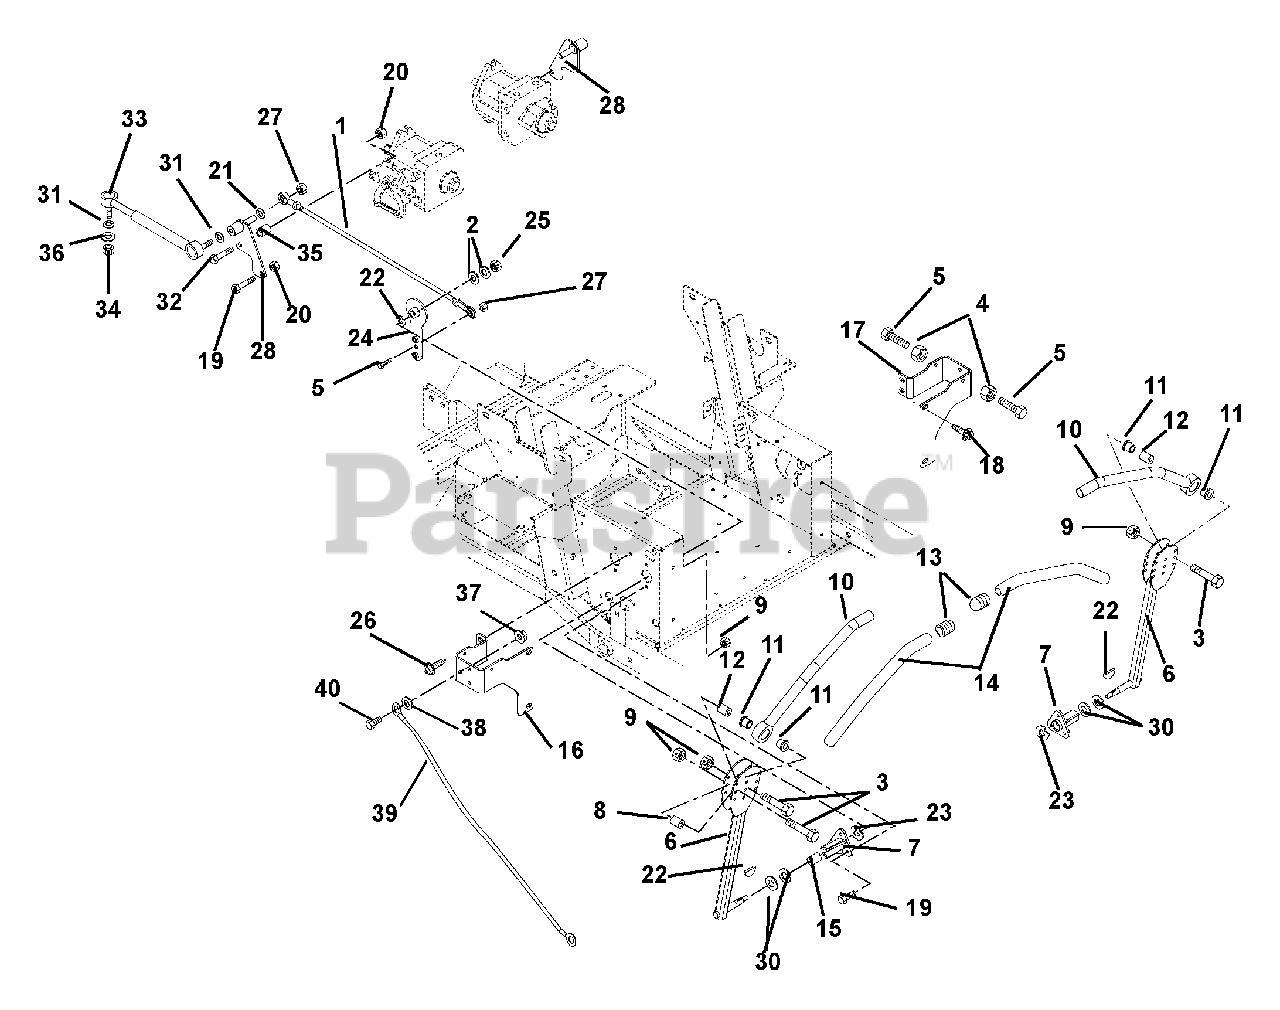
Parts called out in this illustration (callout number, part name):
1	Assembly, Steering Rod .38Rod x 21.65
2	Washer, Flat Steel .408 x .812 x .065
3	Bolt, Hex .31-18 x 1.75 Grade 5
4	Nut, Hex Jam .375-16
5	Bolt, Hex .375-16 x 1.75
6	Weldment, Control Arm
7	Bushing, Flange
8	Eccentric
9	Nut, Locking Top Flange .31-18
10	Handle Weldment-Left Hand
10	Handle Weldment-Right Hand
11	Bushing, Flange Nylon .762 x 1.48 x .44
13	Caplug, Handlebar
14	Grip, Handlebar
15	Bushing .625 x .75 x .50
16	Bracket, Stop Right Hand
17	Bracket, Stop Left Hand
18	Screw, Tapping .38-16 x .75 Hex Washer Head
19	Bolt, Hex .31-18 x .75 Grade 5
20	Nut, Locking Top Flange .31-18
21	Washer, Locking .38 x .094 Regular
22	Key, Woodruff .13 x .63
23	Washer, Wave
24	Weldment, Pivot Arm
25	Nut, Locking Top Flange .38-16
26	Screw, Tapping .38-16 x .50 Hex Washer Head
27	Nut, Locking Jam Center .375-16
28	Weldment, Return to Neutral/Damper/Rod End
29	Bolt, Hex .38-16 x 1.25 Grade 5
30	Washer, Flat Steel .63 x 1.005 x .062
31	Washer, Locking .31 x .078
32	Bolt-Hex .31-18 x 1.25 Grade 5
33	Damper, Control
34	Nut-Locking-Nylon M8-1.25
35	Spacer .318 x .43 x .375
36	Washer, Flat Steel .38 x .875 x .083
37	Nut, Locking Top Flange .25-20
38	Washer, Flat Steel .265 x .50 x .087
39	Cable, Seat Prop
40	Bolt, Hex .25-20 x .75 Grade 5
